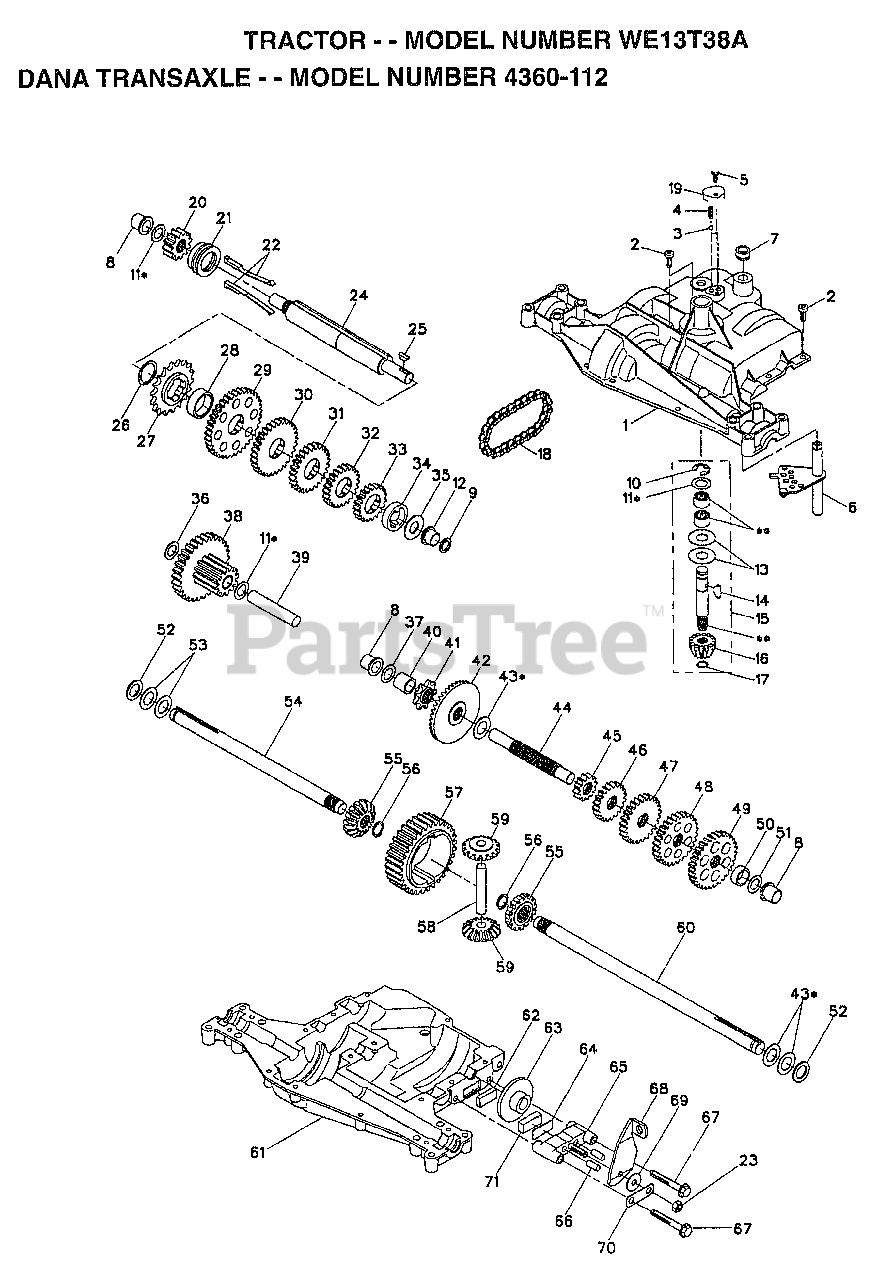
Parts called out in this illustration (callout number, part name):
1	HOUSING.UPPER.DANA.(5305J)
4	"SPRING, DETENT LT"
5	SCREW.TAPPING.1/4-20X.734
6	KIT SHIFTER ASM
9	SEAL.OIL.DAN.5508
10	RETAINING RING LT
11	ASM KIT SHIM 4689
12	BEARING.FLNG.5511
13	WASHER T
14	KEY WOODRUFF-DANA
15	AS KIT INPUT SHFT
16	PINION 14T T
17	"RING,RETAINING LT"
18	"CHAIN,24 PTCH LT"
19	COVER.DETENT.(5584)
20	GEAR.SPUR.12T.(5627)
21	CLUTCH.COL.5467
22	ASM KIT CLTCH KEY
23	NUT.LOCK.5/16-24
24	SHAFT INTERM DANA
25	WOODRUFF KEY
26	"RING,RETAINING LT"
27	SPROCKET 18T T
28	SPACER YT
29	GEAR SPUR 37 TTH
30	GEAR SPUR 30T
31	GEAR 25T LT
32	GEAR SPUR 22 TT
33	SPUR GEAR 19T
34	SPACER
35	"WASHER, PLAIN LT"
36	WASHER 045
37	WASHER 031
38	ASSY.GEAR.6153 12T&30T
39	SHAFT IDLER
40	SPACER T
41	SPROCKET 9T LT
43	ASM KIT SHIM
44	SHAFT T
45	GEAR SPUR 12 TTH
46	GEAR SPUR 20T
47	"GEAR, SPUR 25T LT"
48	GEAR 28T T
49	"GEAR, SPUR 31T LT"
51	WASHER 060
52	NEOPRENE WASHER
53	WASHER 031
54	AXLE.LH(5528-1)
55	GEAR 15T T
56	RING.RETAINING.(5270)
58	SHAFT T
59	GEAR 1ST T
60	AXLE.RH.(5528-2) DANA
61	HOUSING LOWER TNS
62	PUCK T
63	BRAKE DISC. T
64	SPACER LT
66	PIN T
67	SCREW.(5562) .5/16-18X2.35
69	WASHER LT
70	BRACKET, ANTI-ROTATION
71	PUCK T
